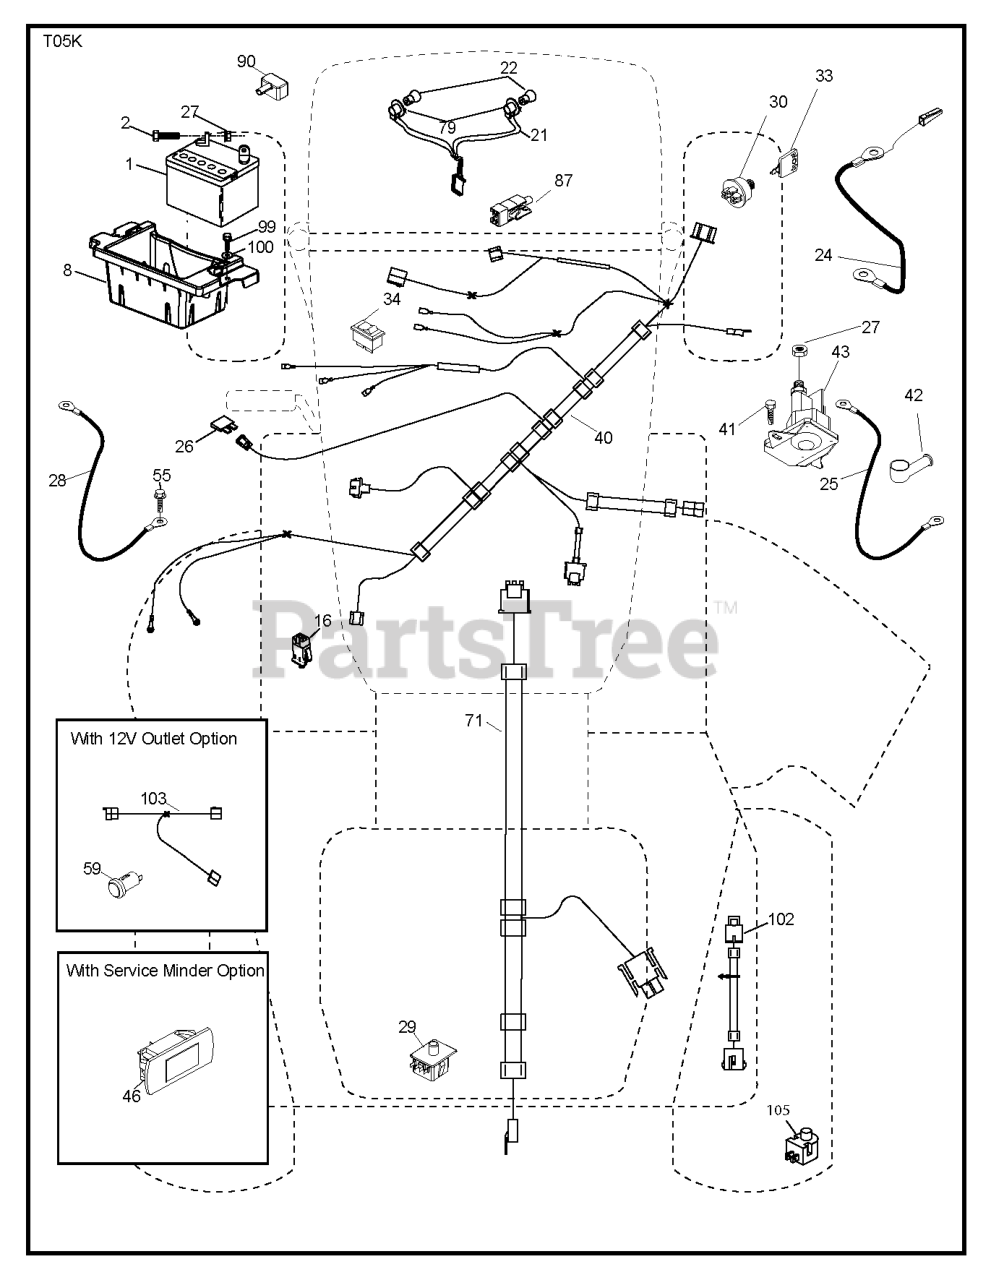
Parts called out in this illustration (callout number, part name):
1	Battery 12 Volt 25 Amp
2	BOLT.HEX.1/4.X.3/4.DICHROMATE
8	TRAY.BATTERY BOX.FRONT
16	SWITCH INTERLOOK PUSH-IN
21	HARNESS.LIGHT W/4152J BULBS
24	CABLE.FRBATT.W/WIRE.8GA.8
25	CABLE.STARTER.8GA.17.5
26	FUSE 20AMP
28	CABLE.GROUND.21"BLK.8GA.90T
29	SWITCH.SEAT.DP W/RAMPS
30	SWITCH.IGN.DELTA.W.LGH.ROS
33	KEY.CHAIN.BLISTER.PACK.GEN.USA
40	HARNESS.IGN.DASH.CBL.YTGT.PRED
41	SCREW
42	TERMINAL COVER
46	GUAGE.SRVCMNDR.HRMTR.
55	SCREW 5/16"
71	HARNESS-CHASSIS SUB
79	BULB HOLDER ASM.
87	SWITCH.INTRLCK.CLUTCH.
90	COVER.TERMINAL.BATTERY
99	SCREW HEXWSHR 1/4-20X3/4
102	HARNESS PIGTAIL PCH TEX ROS
105	REVERSE SWITCH
